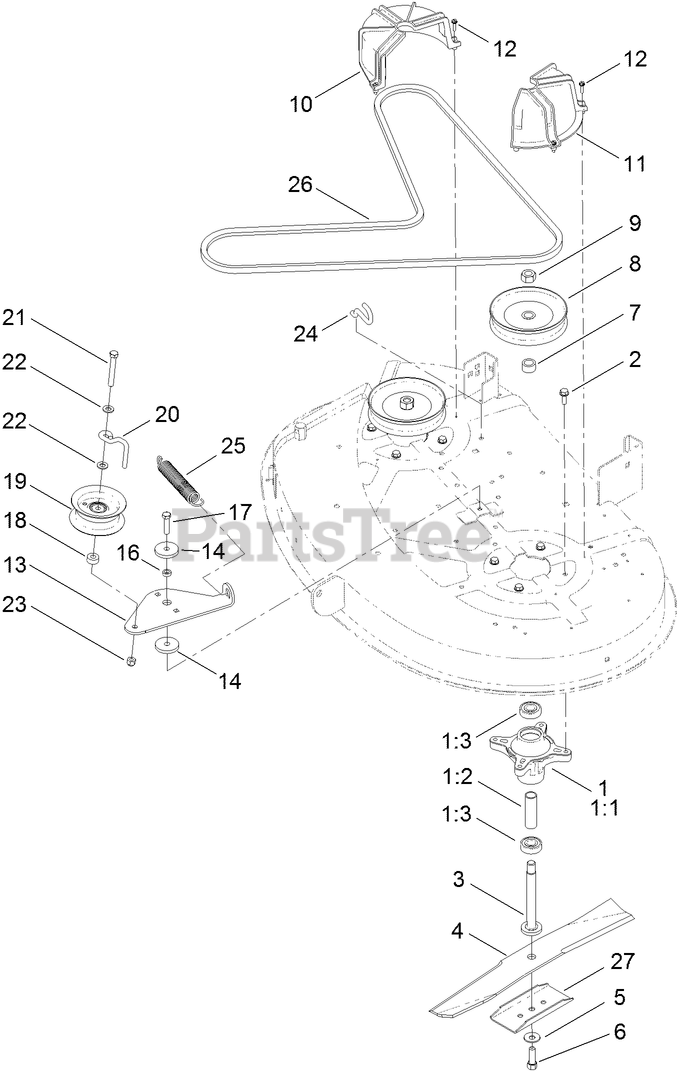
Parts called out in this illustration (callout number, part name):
1:2	SPACER
2	SCREW-TAPTITE
3	SHAFT-SPINDLE
5	WASHER-BELLEVILLE
6	SCREW-HH
7	SPACER-PULLEY
8	PULLEY
9	NUT-HEX
10	GUIDE-BELT, RH
11	GUIDE-BELT, LH
12	SCREW-SHWH, THREAD FORMING
13	ARM-IDLER
14	WASHER-PLAIN
16	SPACER
17	SCREW-HH
18	SPACER
20	GUIDE-IDLER, BELT
21	SCREW-HH
22	WASHER-FLAT
23	NUT-HF, NI
24	HOOK-RETURN, SPRING
25	SPRING-EXTENSION
27	STIFFENER-BLADE
